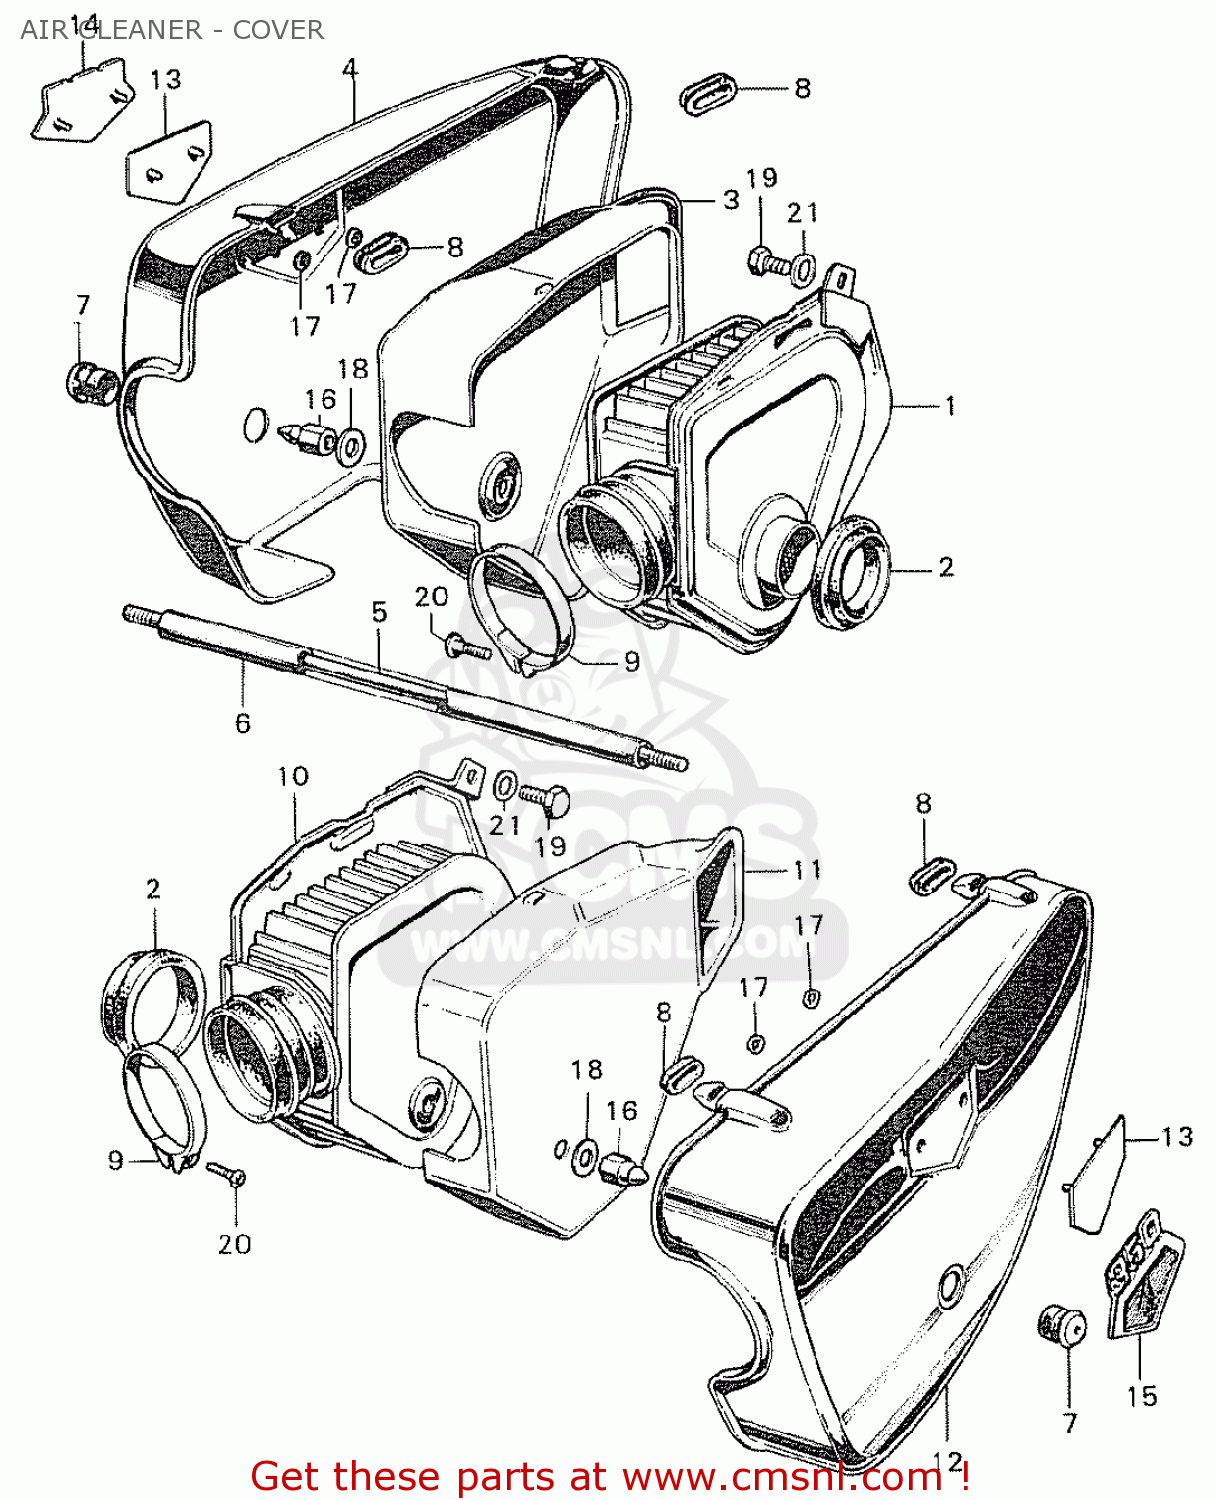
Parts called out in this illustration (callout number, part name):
1	ELEMNT,CLEANER
2	TUBE,CLEANERJOINT
3	CASE,AIR CLEANER
4	COVER,R.CLEANER
5	BAR,ELEMENT SETT.
6	COLLAR,SETTINGBAR
7	GROMMET,
8	GROMMETA,CASE
9	BAND,CONNECTING
10	L,ELEMNT,CLEANER
11	CASE,AIR CLEANER
12	COVER,L.CLEANER
13	EMBLEM AC COVER
16	NUT,ELEMENT SETT.
17	NUT PUSH 3MM
18	WASHER,SETTING
19	BOLT,HEX 6X12
20	SCREW,CROSS,5X16
21	WASHER,PLAIN, 6MM
